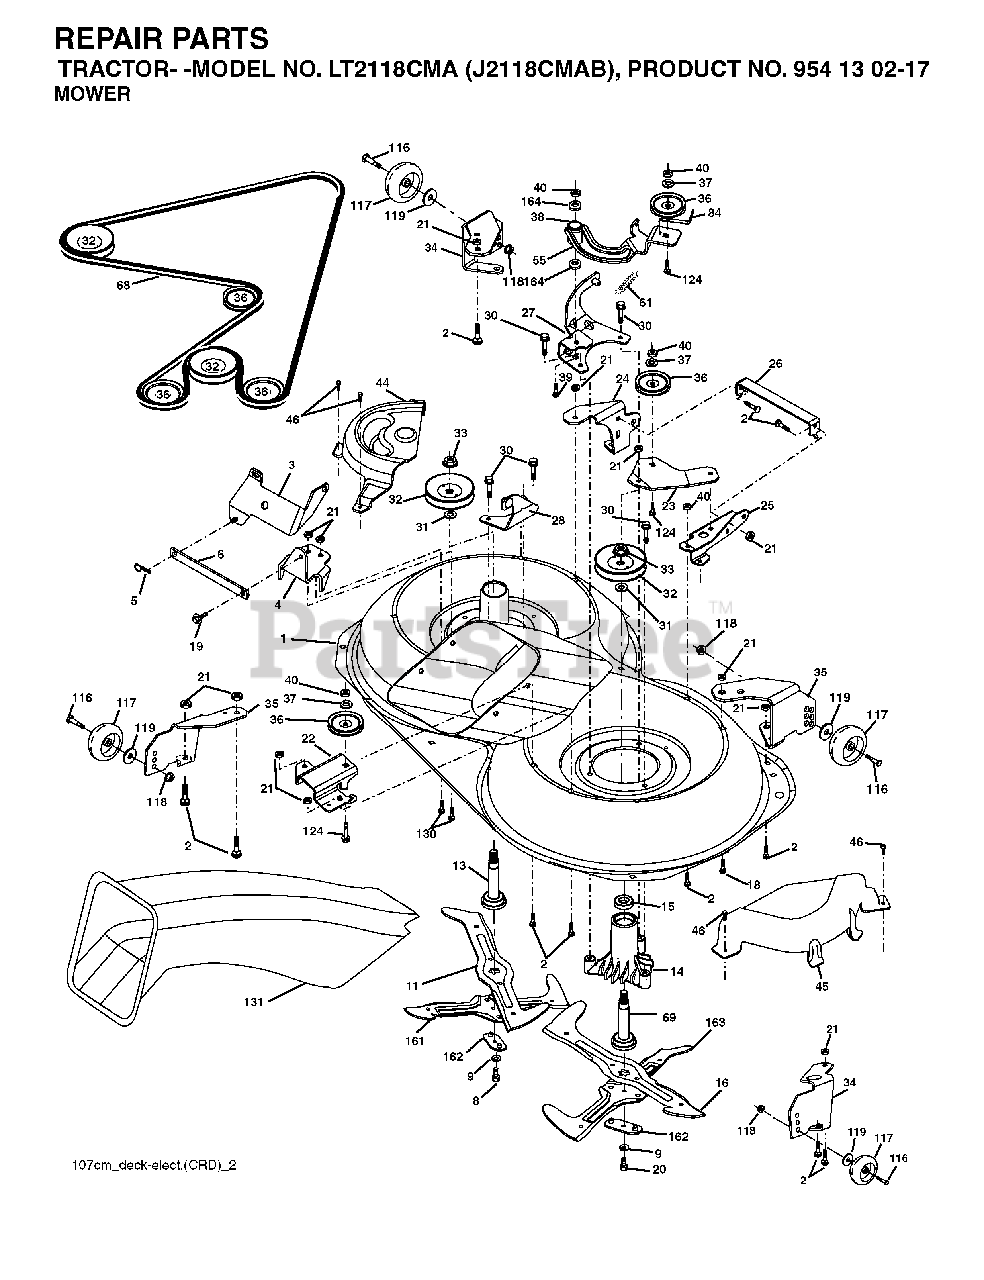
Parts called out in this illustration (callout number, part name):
2	BOLT
3	BRACKET
5	RETAINER-SPRNG RB
6	BAR SWAY
9	LOCKWASHER
11	BLADE.3N1.LH.CRD
13	SHAFT ASM VENT
14	HSG MANDREL
16	BLADE.3N1.RH.CRD
19	BOLT SHD 5/16-18
21	LOCKNUT
22	BRACKET
23	BRACKET
26	BRACE
27	BRACKET
30	SCREW, WASHER HEAD
31	WASHER.SPACER.MANDREL
33	NUT, FLG TOPLOCK 9/16"
36	PULLEY.IDLER.4.25
40	LOCKNUT
45	MANDREL COVER
46	SCREW.1/4-20X5/8
55	ARM IDLER
68	HEX-BELT 107 MOWER
69	SHAFT.ASM.W/LWR.BRG.RH.THREAD
84	KEEPER, BELT IDLER
116	SHOULDER BOLT
117	WHEEL GAGE DONUT
118	LOCKNUT
119	WASHER
124	BOLT.3/8-16X1.50
131	CHUTE BAGGER
164	BRNG T
